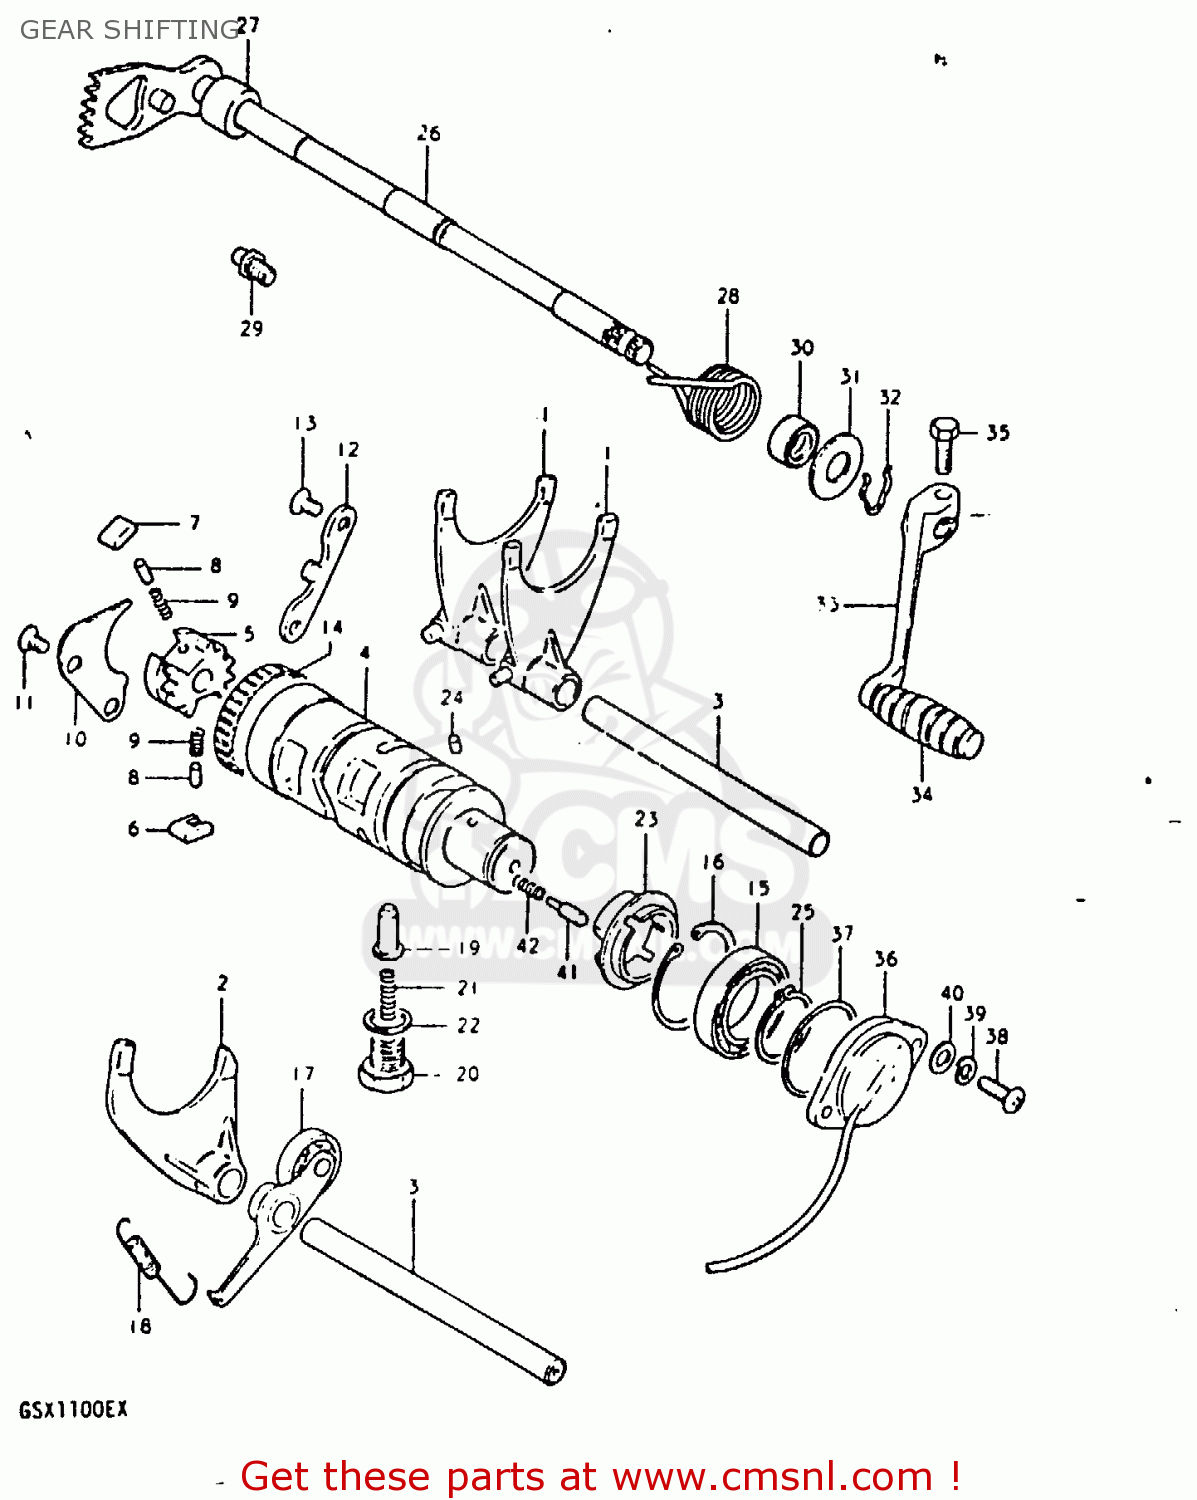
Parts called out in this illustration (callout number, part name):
1	FORK,GEAR SHIFT NO.1
2	FORK,GEAR SHIFT NO.2
3	SHAFT,GEAR SHIFT FORK
4	CAM,GEAR SHIFT
5	RETAINER,GEAR SHIFT CAM
6	PAWL,GEAR SHIFT NO.1
7	PAWL,GEAR SHIFT NO.2
8	PIN(5X8)
9	SPRING
10	LIFTER,GEAR SHIFT PAWL
11	SCREW
12	GUIDE,GEAR SHIFT CAM
13	SCREW
14	BEARING(43X49X12)
15	BALL BEARING
16	CIRCLIP
17	STOPPER,GEAR SHIFTING
18	SPRING
19	STOPPER,GEAR SHIFT CAM NO.2
20	HOLDER,GEAR SHIFT CAM STOP SPR
21	SPRING
22	GASKET(14X19.2X2) (NAS)
23	PLATE,GEAR SHIFT CAM STOPPER
24	PIN 4X6
25	CIRCLIP
26	SHAFT,GEAR SHIFT
27	SPACER(12X20X15.3)
28	SPRING
29	STOPPER,GEAR SHIFT CAM
30	OIL SEAL
31	WASHER (12.5X27X1.6)
32	SPRING,RETAINER
33	LEVER ASSY,GEAR SHIFT
34	RUBBER,GEAR SHIFT PEDAL
35	BOLT
36	BODY, SHIFTING SWITCH
37	O RING(D:2.4,ID:36.5)
38	SCREW
39	LOCK WASHER
40	WASHER
41	PIN(5X15.5)
42	SPRING
